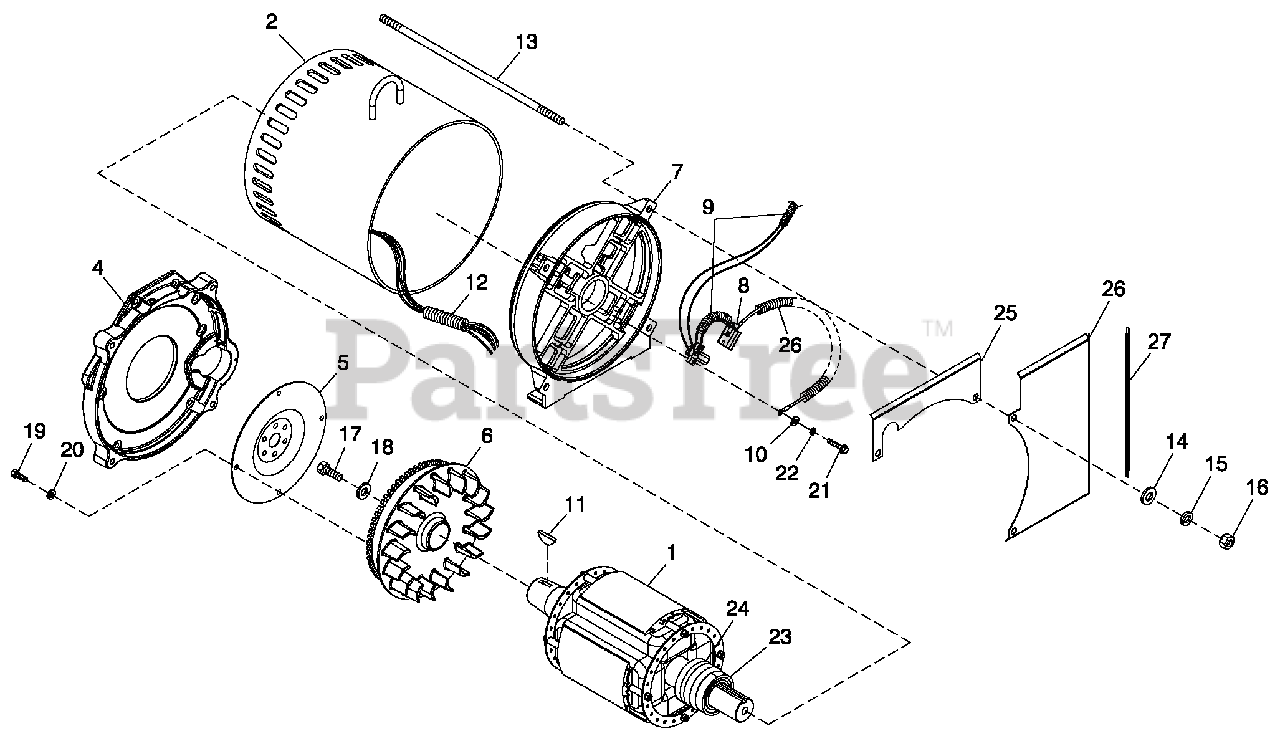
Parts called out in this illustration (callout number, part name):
1	RTR 390 45AD1 CPL
2	STR 390 45AD1 CPL
4	ENGINE ADAPTER
5	FLEXPLATE
6	ASSY FLYWHEEL CPL W/40MM FAN B
7	REAR BEARING CARRIER 390/DRCT
8	ASSY BRUSH HOLDER 390/HSB
9	CONDUIT FLEX .38" ID (60")
10	WASHER FLAT #8 ZINC
11	KEY WOODRUFF #E
12	CONDUIT FLEX 1.0" ID (35" LG)
13	STUD M 14-2.0 570 G5 ZINC
14	WASHER FLAT M14
15	WASHER LOCK M14
16	NUT HEXM14-2.0G8YEL CHR
17	SCREW HHCM16-2.0X 45 G8.8
18	SPACER .69 X 2.75 X .37 ST/ZNC
19	SCREW HHC M10-1.50 X 16 G10.9
20	WASHER LOCK M10
21	SCREW HHTT M4-0.7 X 25 BP
22	WASHER LOCK #8-M4
23	BALL BEARING-45 MM
24	SLIP RING MACHINED
25	GUARD REAR BEARING CARRIER
26	GUARD REAR BEARING CARRIER
27	TRIM VINYL BLACK 1/8GP (16.5"LG)
